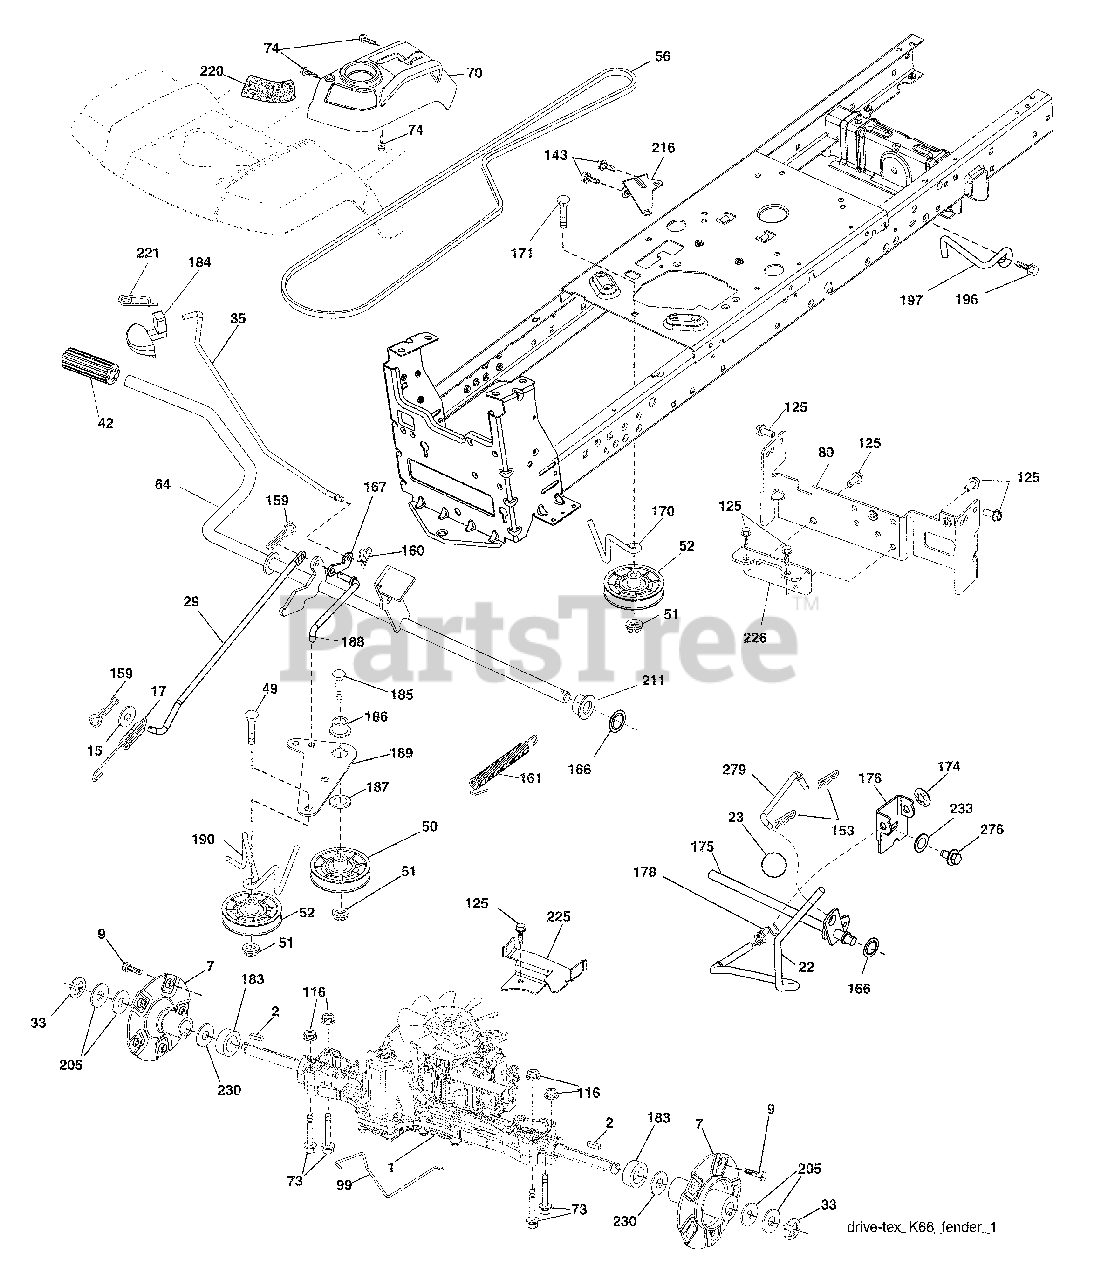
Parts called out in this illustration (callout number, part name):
1	Transaxle, TuffTorq K66
7	Hub Asm. Wheel
9	Bolt Hub Wheel
15	Washer 13/32 x 13/16 x 16 Ga.
17	Spring, Brake
23	Knob Deluxe 1/2-13 unc
29	Rod, Brake
35	Rod, Brake, Park
42	Cover, Foot Pedal
50	Pulley Idler Flat
51	Lock Nut 3/8-16
52	Idler V-Groove 910" Offset
56	V-Belt, Drive
64	Shaft Asm. Pedal Brake Control
70	Console Asm.
73	Bolt Hex Flghd 5/16-18 Gr. 5
74	Screw Hx Wsh Hi-Lo 1/4 x 1/2 unc
80	Strap Torque
99	Rod Bypass
116	Nut Lock Hex Flange 5/16-18
125	Screw 5/16-18 x 3/4
143	Screw 5/16-18 x 1/2
153	Retainer Spring
159	Pin Cotter 1/8 x 3/4
160	Retainer Clip
161	Spring, Return, Clutch
166	Nut Push .625
167	Latch Brake Parking
170	Keeper Belt Centerspan
175	Shaft Asm. Shift
176	Arm Clevis Rod Shift
178	Spring Shift
183	Spacer Axle
184	Handle Parking Brake
186	Spacer Retainer
187	Washer
188	Link Clutch Ground Drive
189	Bellcrank Ground Drive
190	Keeper Bellcrank Ground Drive
196	Screw 3/8-16 x 1
197	Bracket Clutch Anti-Rotation
205	Washer 1 1/32 x 1 5/8 x 16 Ga.
211	Bearing Nylon
216	Bracket Pulley Idler
220	Reflector RH
221	Retainer Spring Clip Handle
225	Keeper Belt Trans.
226	Bracket Mount Torque
230	Hardened Washer
233	Washer Serrated
276	Bolt Fin Hex 7/16-14 x 1 Gr. 5
279	Link Asm. Shift
